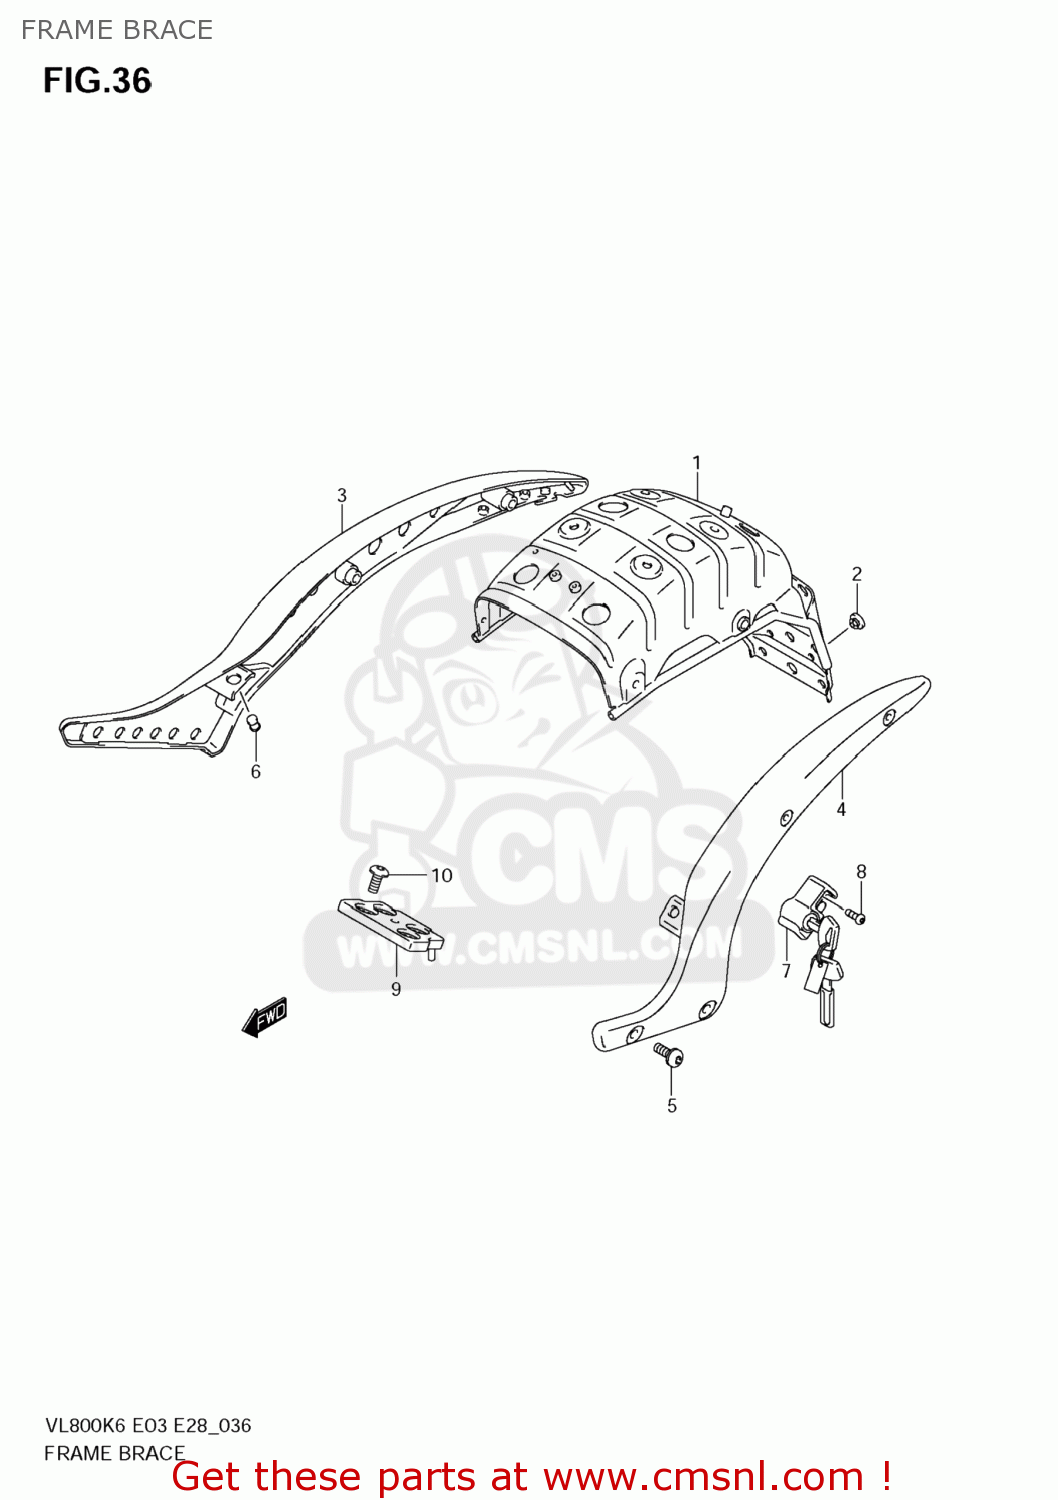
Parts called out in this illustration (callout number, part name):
1	BRACE,RR FRAME
2	CUSHION
3	GRIP,FRAME HANDLE,R
4	GRIP,FRAME HANDLE,L
5	BOLT(10X25)
6	PLUG(OD:9)
7	LOCK SET,HELMET
8	SCREW(6X14)
9	BRACKET,FUEL TANK
10	BOLT(8X16)
